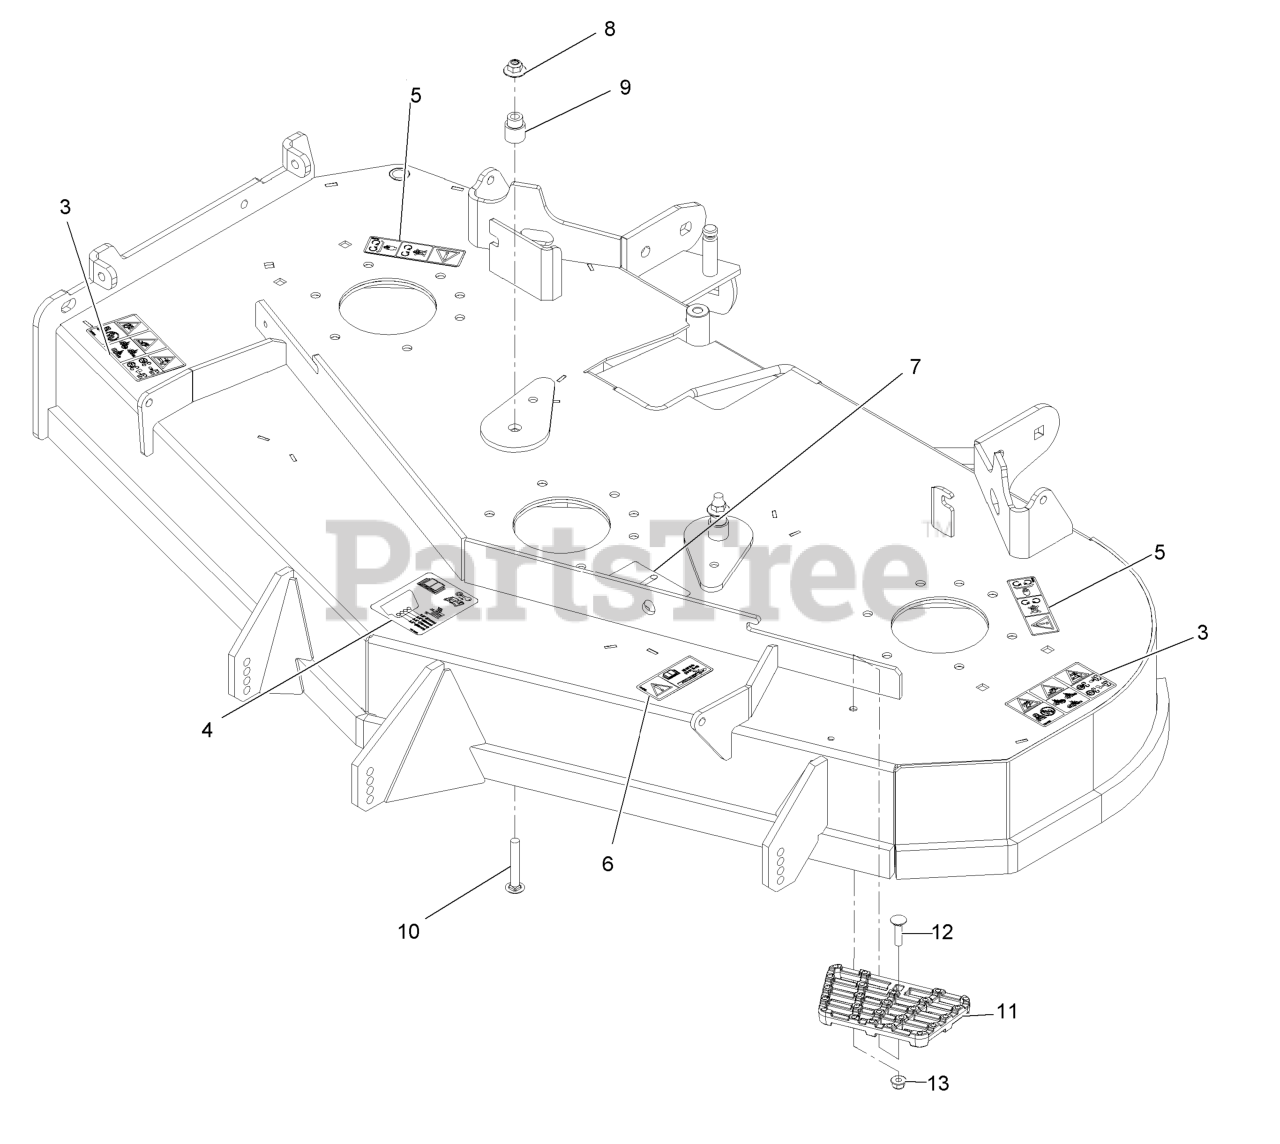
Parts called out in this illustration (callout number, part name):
3	Decal-Danger Thrown Objects
4	Decal-Roller, Anti-Scalp
5	Decal-Cover, Missing
6	Decal-Bolt Torque
7	Decal-Belt Routing
8	Nut-Nyloc 3/8-16 Flg
9	Bushing, Idler
10	Bolt-Carriage 3/8-16 X 2 1/2
11	Step-Deck
12	Bolt-Carriage 5/16-18 X 1 1/4
13	Nut-Nyloc 5/16-18 Flg
